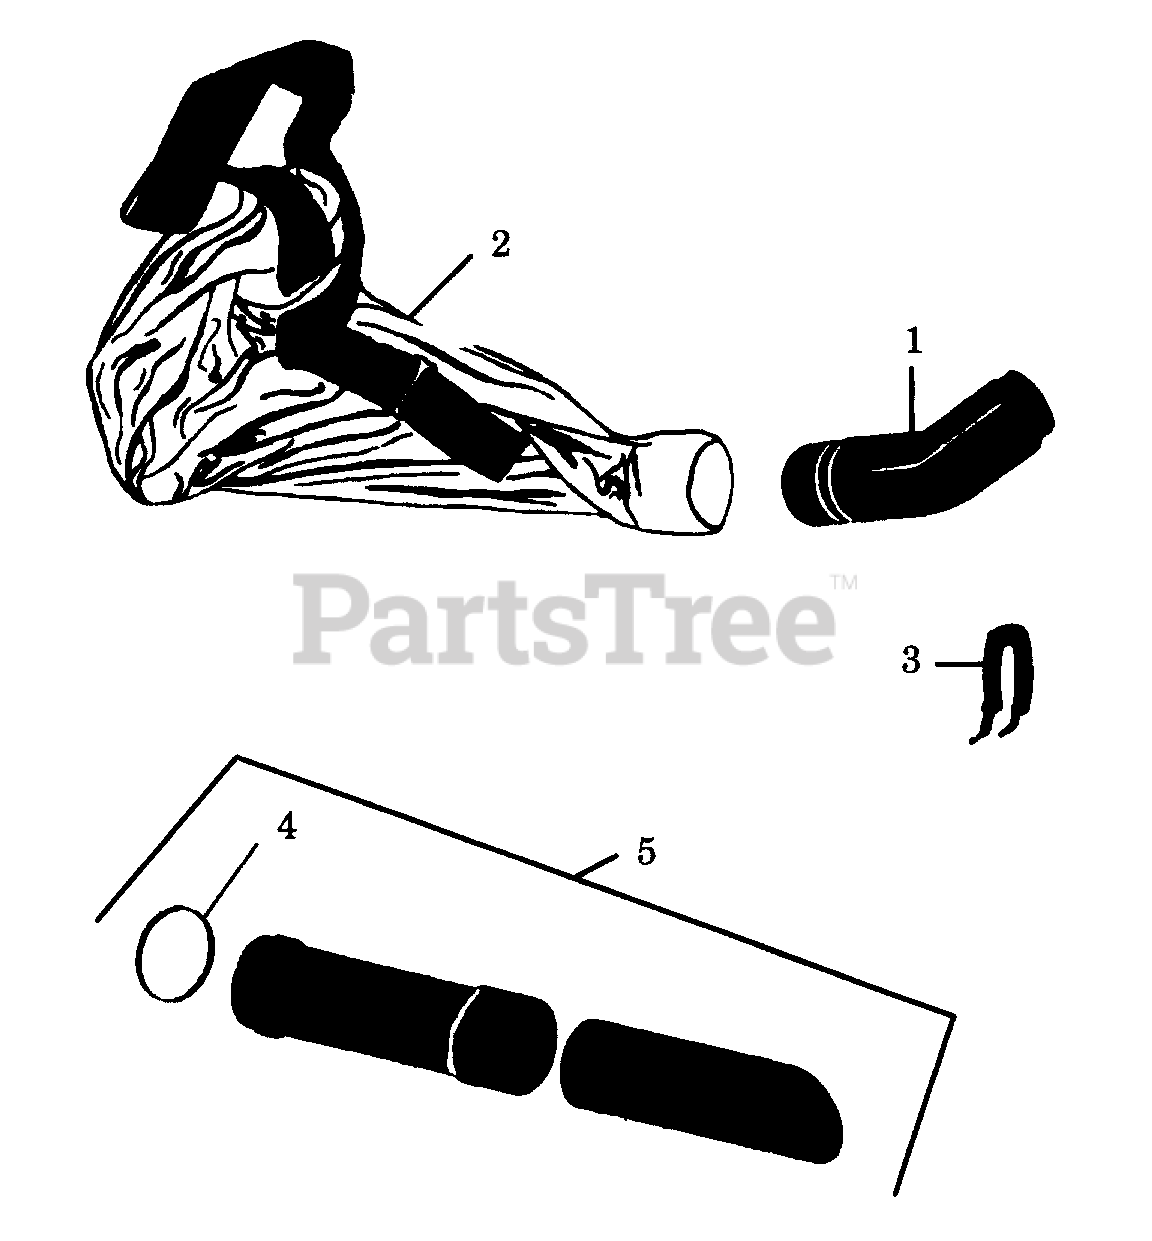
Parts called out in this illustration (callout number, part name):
2	Vacuum Bag Kit
3	Rear Handle Ass'y.
4	Spacer
5	Vacuum Tube Kit
